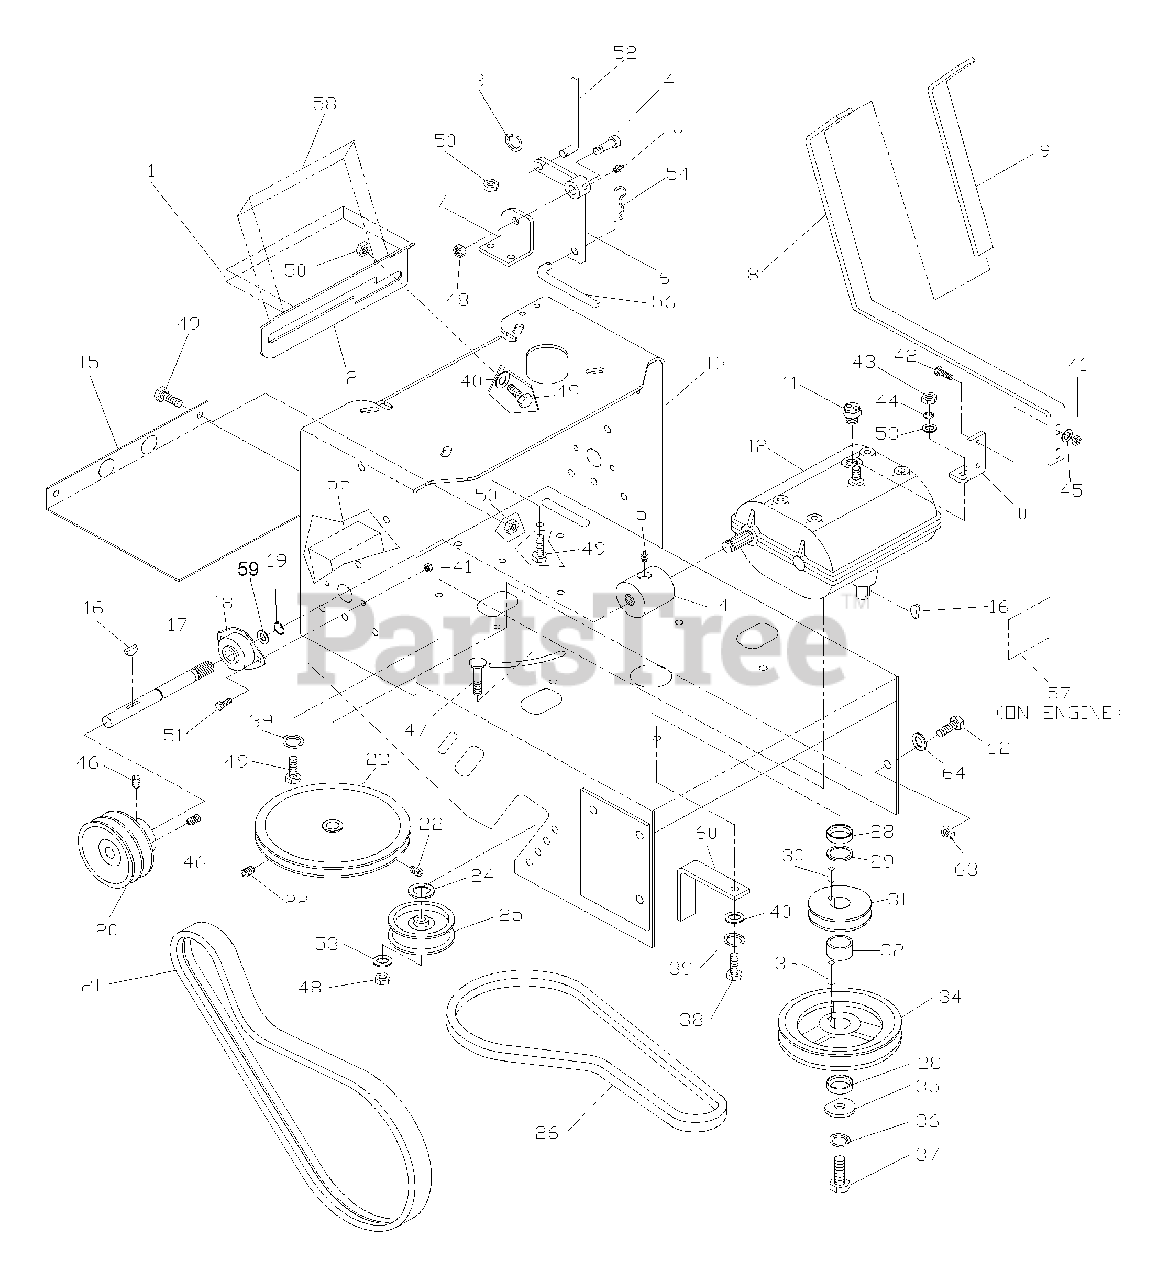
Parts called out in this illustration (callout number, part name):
1	DECAL,SHIFTER
2	SHIFTER PLATE
4	SB 1/2C X 3/4
5	ZERK1/4-28 STRHT
8	SHIFTER ARM
9	SHIFTER GRIP
10	SHIFTER BRKT.
11	TRANS. SWITCH
12	TRANSMISSION
13	REAR DECK W/DCLS
15	LOWER BELT SHIELD
16	#9 WOODRUFF KEY
17	DRIVE SHAFT
19	RETAINER RING
20	DRIVE PULLEY
21	DRIVE BELT
22	1/4 NYLOC SETSCW.
23	INPUT PULLEY
24	1/2 FLAT WASHER
25	IDLER PULLEY
26	BELT, TRANSMISSION
29	MACH. BUSHING
30	KEY 1/4SQ. X 1/2
33	KEY 1/4SQ. X 1 1/8
34	ENGINE PULLEY
35	HEAVY WASHER
36	SLW 7/16 STD
37	HCS 7/16F X 1.5 GR 5
38	HCS M8-1.25 X 30MM
39	SLW 5/16 STD
40	5/16 FW STD
42	HCS 1/4C X 1
44	SLW 3/8 STD
45	FW 1/4 STD
46	5/16 NYLOC SETSCW
47	RHSNB 3/8C X 2
48	HLN 3/8C CENTER P.
49	HCS 5/16C X 3/4
51	HCS 1/4C X 5/8
53	FW 3/8 STD
54	#4 HAIRPIN
55	DANGER DECAL
57	EXHAUST DECAL
58	DECAL, CLUTCH
59	MACH. BUSHING
60	BELT GUIDE,LONG
62	HCS, 7/16C X 1 1/2
63	NUT, 7/16C, CENTER LOCK
64	WASHER, 7/16
